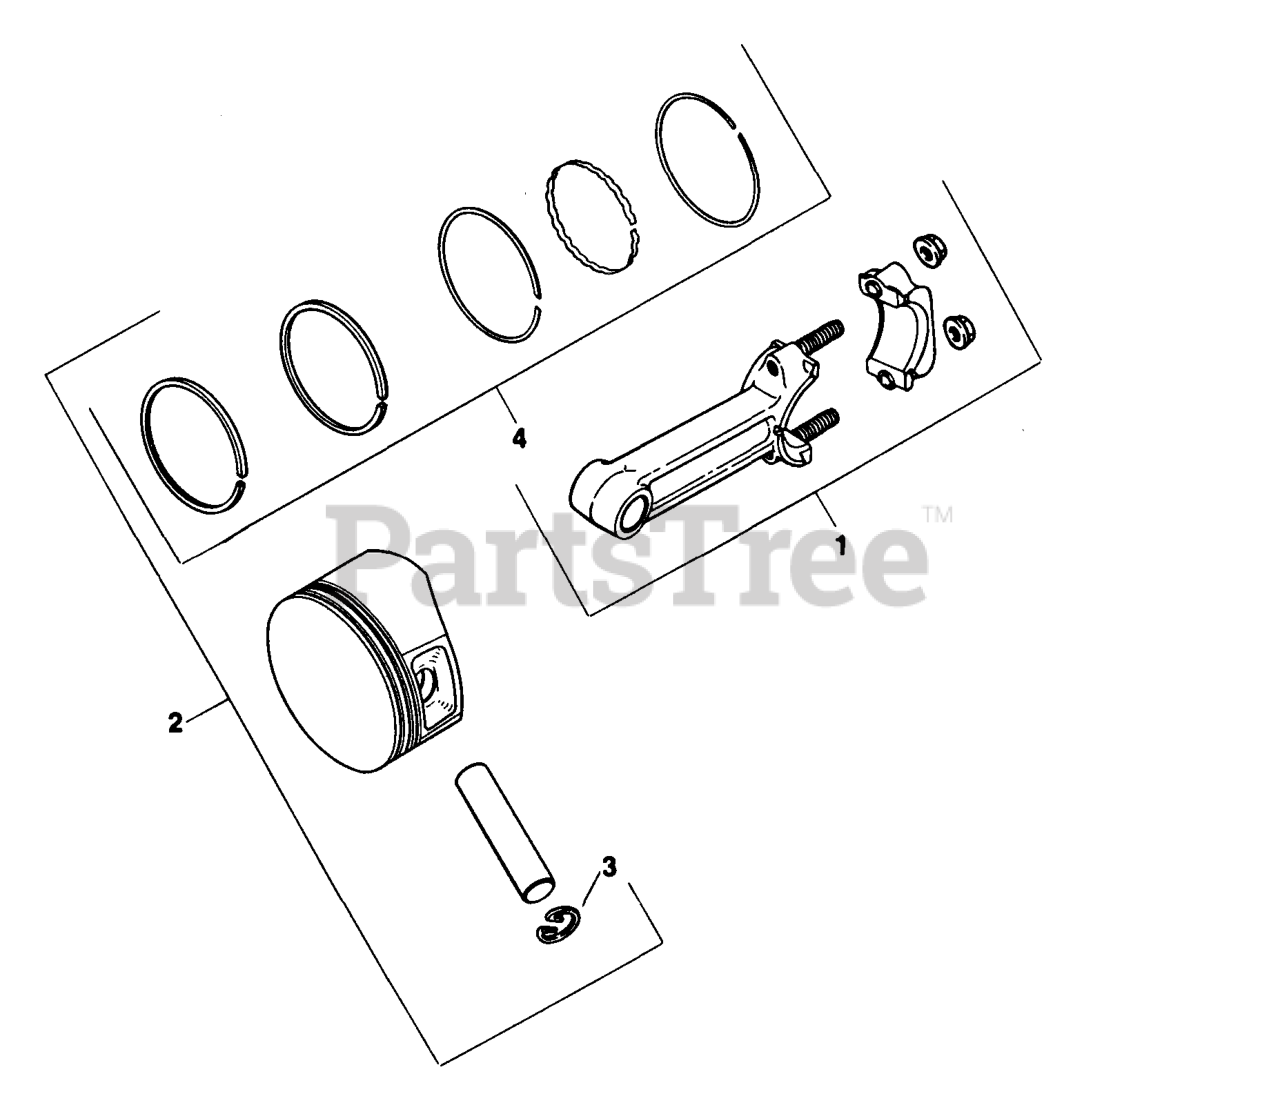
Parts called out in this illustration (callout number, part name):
1	Connecting Rod (Std.)
1	Connecting Rod (.010)
2	Piston W/Ring Set (Std.)
2	Piston W/Ring Set (.003)
2	Piston W/Ring Set (.010)
2	Piston W/Ring Set (.020)
2	Piston W/Ring Set (.030)
3	Retainer, Piston Pin
4	Ring Set (Std. & .003)
4	Ring Set (.010)
4	Ring Set (.020)
4	Ring Set (.030)
